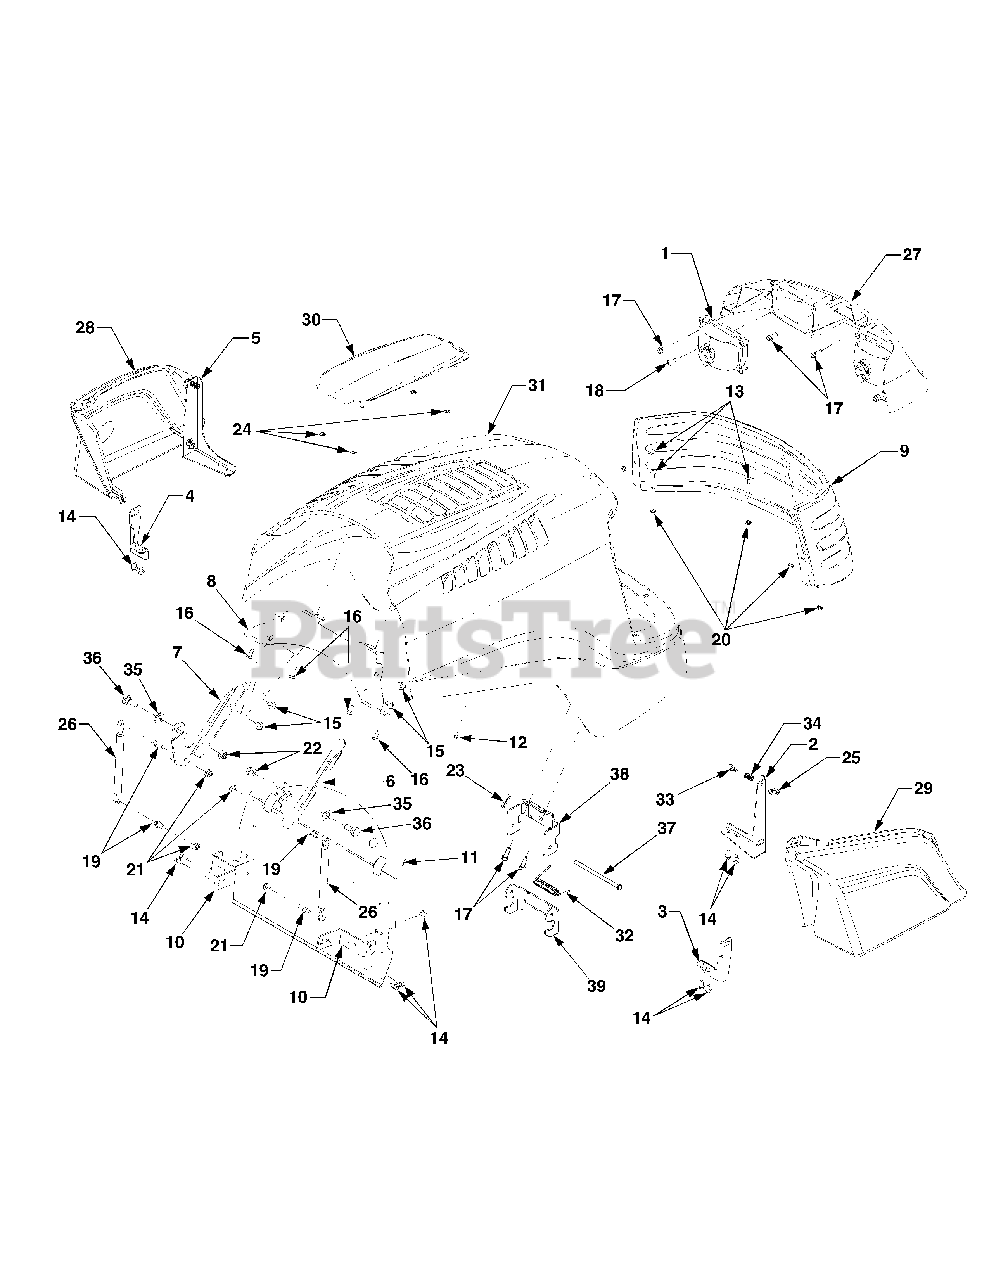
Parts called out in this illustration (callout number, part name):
1	Headlight Assembly
2	Brkt, Side Pnl. Mtg. RH
3	Brkt, Side Pnl. Mtg. RH Rear
4	Brkt, Side Pnl. Mtg. LH Rear
5	Brkt, Side Panel Mtg. LH
6	Bracket, Hinge, RH
7	Bracket, Hinge, LH
8	Bracket, Hood Mounting
11	Shield, Lower Heat
12	Screw, Hex Wash Hd, #8-18 x .375
13	Screw, Truss Hd, 10-24 x .5
14	Screw, Hex Wash Hd Tapp 1/4-20 x .5
15	Screw, Hex Wash Hd Tapp 5/16-18 x .5
16	Screw, Hex Cap 1/4-20 x .62 GR5
17	Screw, Hex Wash. Hd. 1/4-20 x .75
18	Screw, Truss Phil. Hd. 12-16 x .75
19	Stud, Cylinder, 5/16-18 Thrd
20	Nut, Hex Sems, 10-24
21	Nut, Hex Insert Flange Lock, 5/16-18
22	Nut, Hex Insert Flange Lock, 3/8-16
23	Pin, Internal Cotter
24	Nut, Push, .25 ID
25	Latch, 1/4 Turn Panel
26	Cylinder, Gas Spring
27	Bezel, Headlight
28	Panel, Side LH
29	Panel, Side RH
30	Cover, Hood
31	Hood, Service Kit
31	Hood
32	Spring, Torsion
33	Clip, Spring
34	Spring, Compression
35	Washer, Flat, .51 x 1.0 x .060
36	Screw, Shoulder, .5 x .27 Lg 3/8-16
37	Rod, .25 x 4.55
38	Plate, Latch
39	Bracket, Latch Pivot
